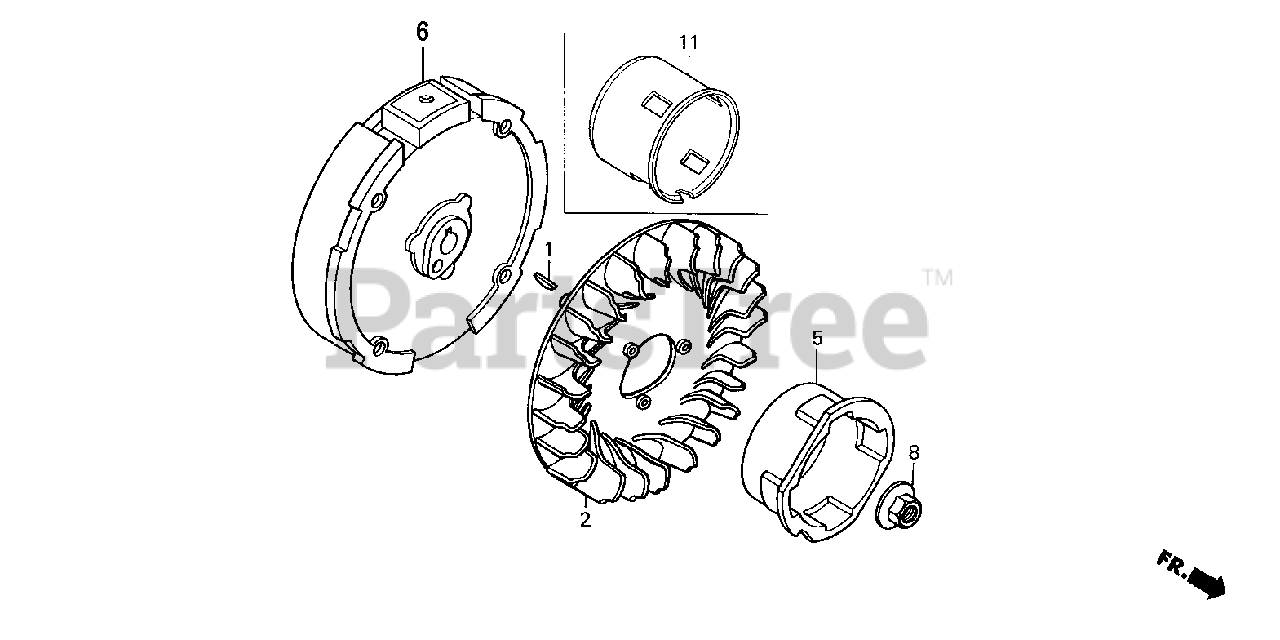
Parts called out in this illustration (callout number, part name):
1	KEY, SPECIAL WOODRUFF (25X18)
2	FAN, COOLING
8	NUT, SPECIAL (14MM)
11	PULLEY, STARTER
